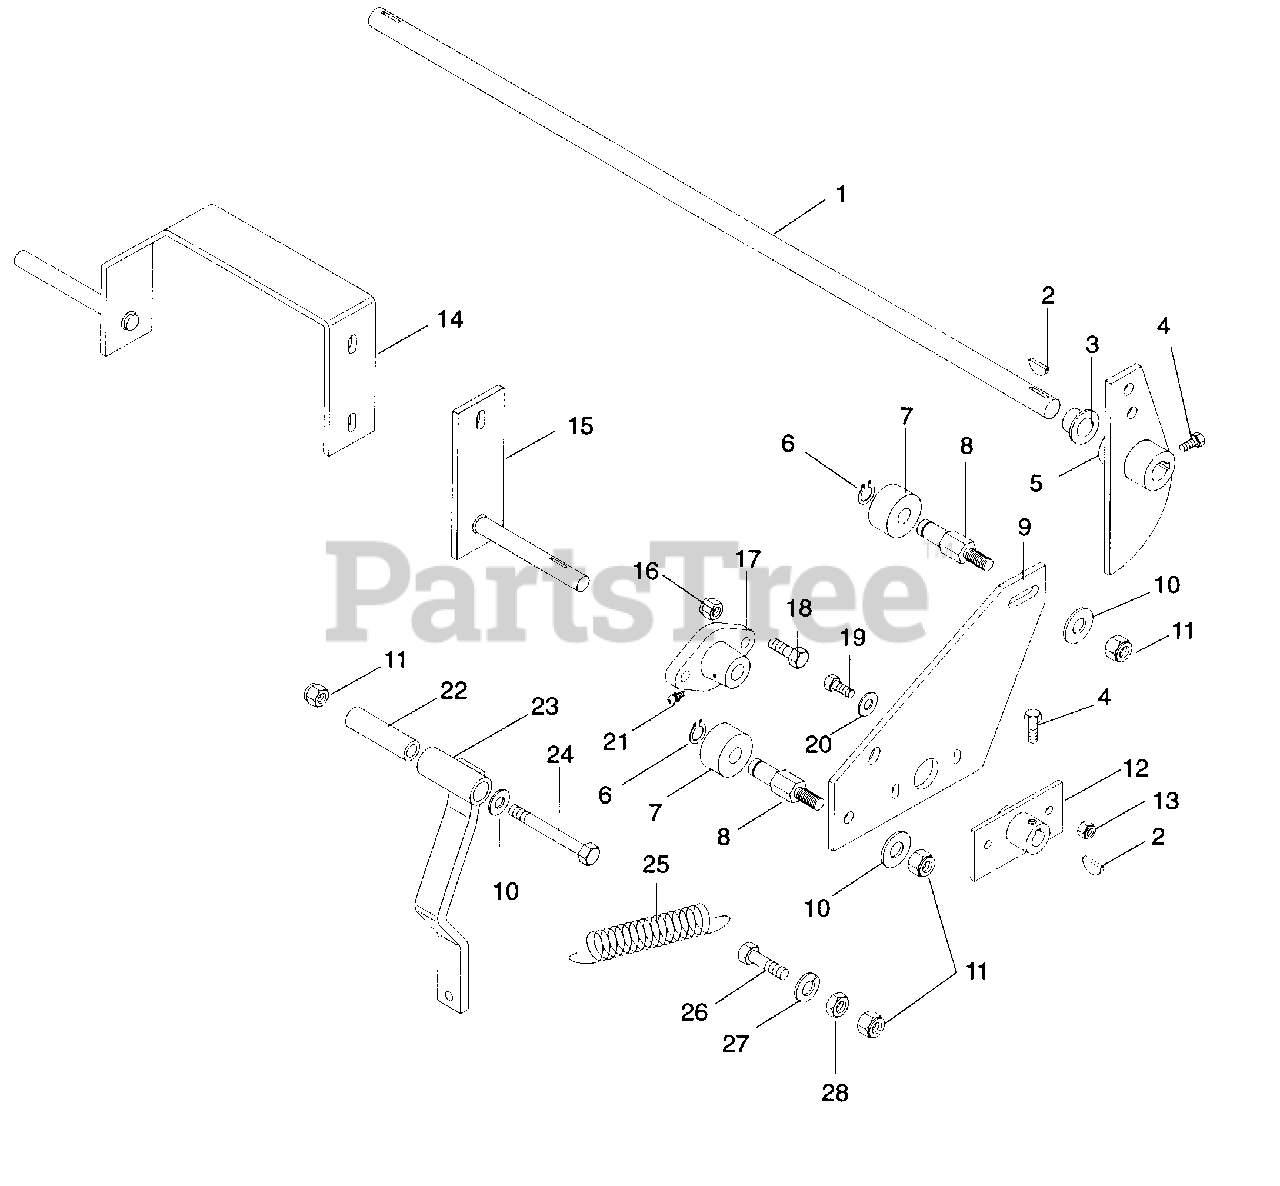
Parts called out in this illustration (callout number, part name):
1	Shaft, Speed Control Cam
2	Key, Woodruff .13 x .75
3	Bushing, Flange .630 x 1.000 x .625
4	Bolt-Hex .25-20 x .50 Grade 5
5	Weldment, Control Cam
6	Ring-Retaining-Internal 2.68 x .049
7	Roller, Nylon
8	Pin, Roller
9	Arm, Speed Control
10	Washer-Flat-Steel .406 x .812 x .065
11	Nut-Locking-Nylon .375-16 Grade 2
12	Weldment, Neutral Adjustment
13	Nut-Locking-Nylon .250-20
14	Weldment, Pump Control, Right Hand
15	Weldment, Pump Control, Left Hand
16	Nut-Locking-Nylon .312-18 Grade 2
17	Bushing, Flanged Support
18	Bolt-Hex .31-18 x 1.00 Grade 5
19	Bolt-Hex .25-20 x .75 Grade 5
20	Washer-Flat-Steel .281 x .625 x .065
21	Fitting-Lube .25-28 x .256
22	Bushing, Steel .385 x .610 x 1.80
23	Weldment, Detent Strap
24	Bolt-Hex .38-16 x 2.75 Grade 5
25	Spring-Tens .063 x .62 x 2.75
26	Bolt-Hex .38-16 x 1.50 Grade 5
27	Washer-Lock .375 x .094
28	Nut-Hex .375-16 Grade 2
